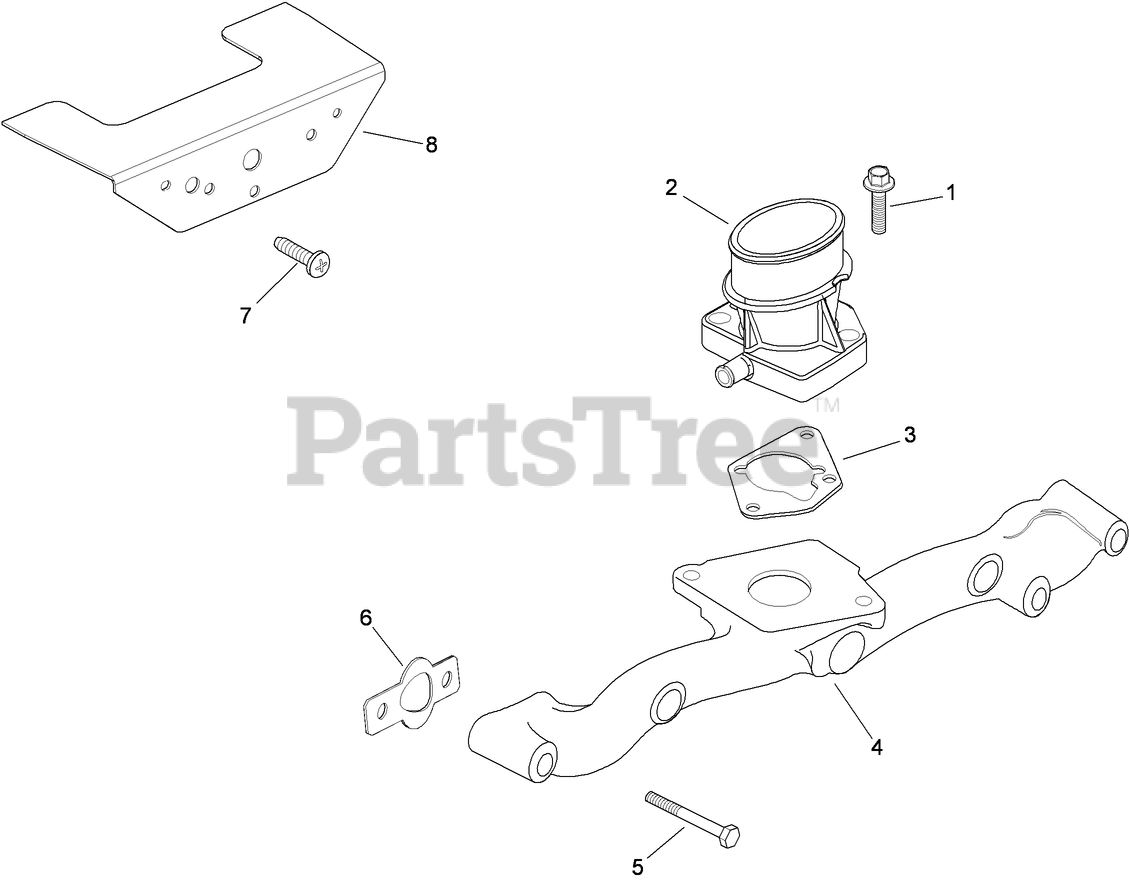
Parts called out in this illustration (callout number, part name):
1	SCREW-FLANGE (M6X1.0X25)
2	Adapter-Air Cleaner, Remote
3	GASKET-BASE, AIR CLEANER
4	Manifold-Intake
5	Screw-HF (M6x1.0x55)
6	Gasket-Manifold, Intake
7	SCREW-PPH (11-16X3/4)
8	Shield-Debris
